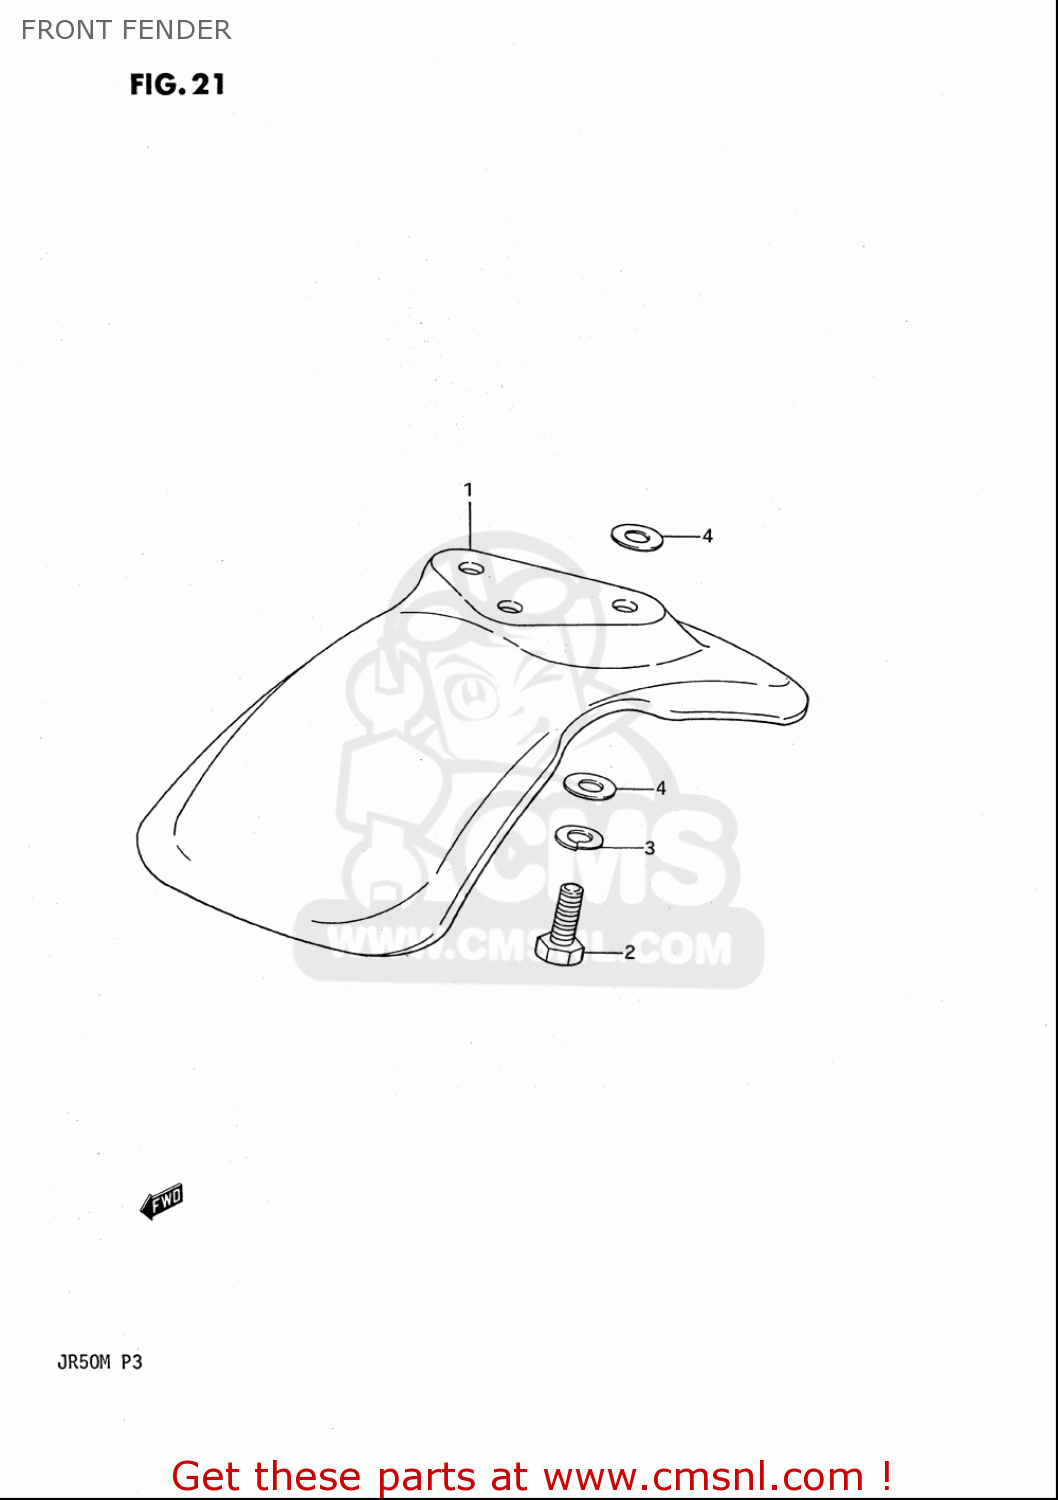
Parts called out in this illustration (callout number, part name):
1	FENDER,FR
2	BOLT
3	WASHER,LOCK
4	WASHER(6.5X18X1)
